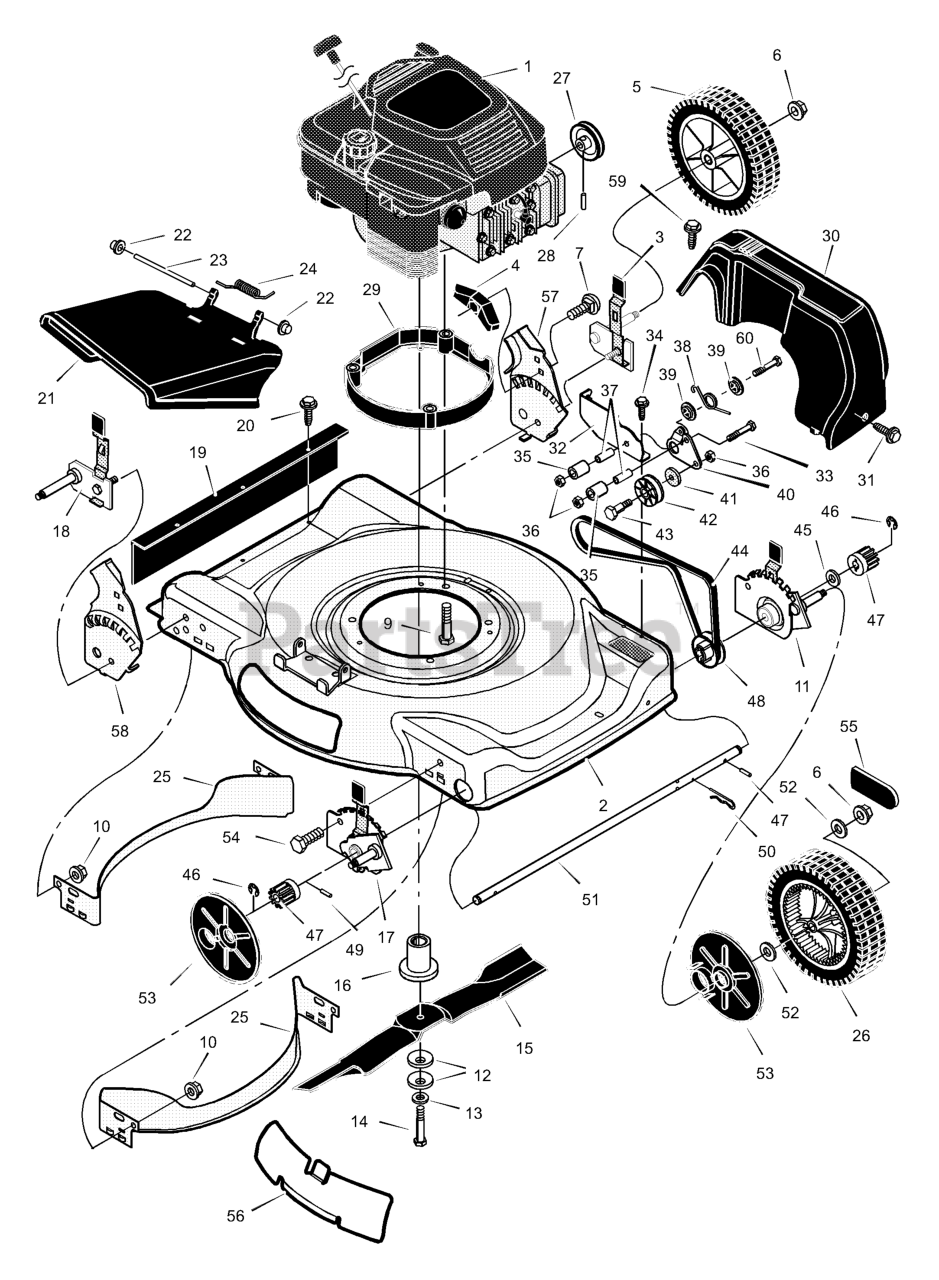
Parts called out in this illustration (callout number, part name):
1	Engine
2	Housing
3	Height Adjuster, Left Rear
5	Wheel and Tire, Rear
6	Locknut, Flange
7	Bolt, Carriage
9	Bolt, Engine
10	Nut
11	Height Adjuster, Left Front
12	Washer, Belleville
14	Bolt, Hex
15	Blade, (3-N-1)
16	Adapter, Blade
17	Height, Adjuster, Right Frt.
18	Height, Adjuster, Right Rr.
19	Guard, Rear
21	Deflector, Chute
22	Push-On Cap
23	Pin, Pivot
26	Wheel and Tire, Drive
28	Pin, Spring
29	Base, Engine
30	Cover, Belt (Black)
32	Bracket, Idler Support
35	Idler, Backside
36	Locknut
37	Bearing
40	Arm, Pivot
42	Pulley, Idler
43	Bolt, Shoulder
44	Belt, Briggs & Stratton
46	Ring, Retainer
47	Gear, Pinion
49	Pin, Drive
50	Pin, Hair
52	Washer
53	Cover, Dust
54	Bolt
55	Hub Cap
56	Plate, Mulcher
57	Bracket, Left Handle
58	Bracket, Right Handle
62	Shield, Debris
68	Bolt, Carriage
